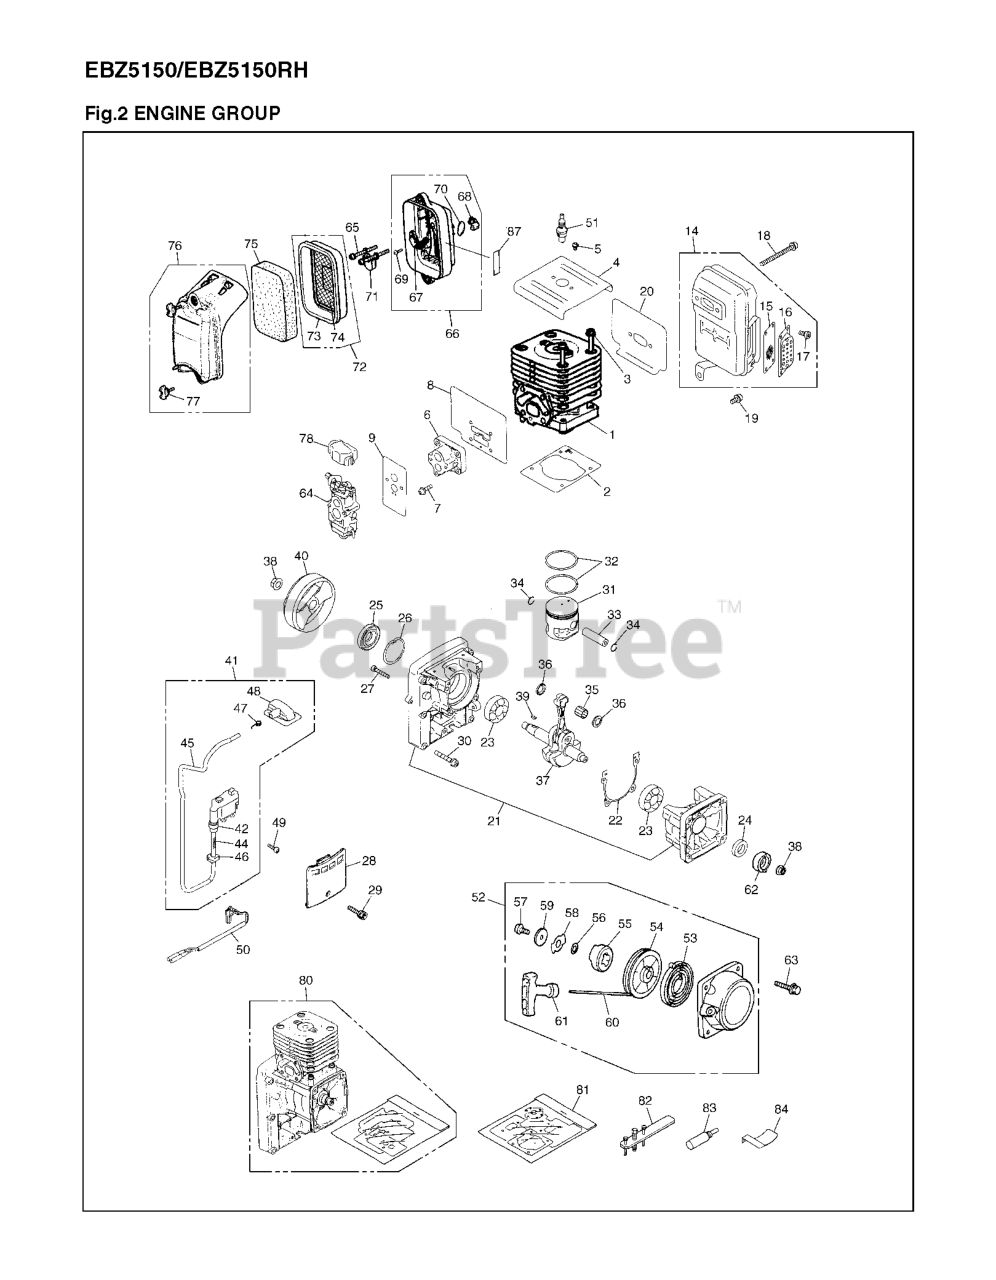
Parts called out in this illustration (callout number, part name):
1	CYLINDER
3	BOLT
4	CYLINDER COVER
6	INSULATION
8	GASKET,INSULATOR
14	MUFFLER ASSY
15	SPARK ARRESTOR SCREEN
16	EXHAUST DUCT
19	RP_BOLT
20	GASKET.MUFFLER
21	CRANKCASE
23	BEARING
26	RING
32	PISTON RING
33	PISTON PIN
34	SNAP RING
37	CRANKSHAFT
39	KEY
40	FLYWHEEL
41	COIL ASSY
42	HUB CAP 848F6L71E0
45	RP TUBE-A
46	GROMMET
50	CORD-COMP
51	PLUG CMR7H
52	STARTER ASSY
54	STARTER PULLEY
55	STARTER PAWL
58	RETAINER
59	WASHER
60	CHORD
62	PULLEY
64	CARBURETOR
66	CARBURETOR BODY
67	PLATE
69	SCREW
72	GASKET
74	SCREEN
75	AIR FILTER
76	COVER ASSY.
80	SHORT BLOCK
80	GASKET,INSULATOR
80	GASKET.MUFFLER
81	GASKET KIT
82	PULLER ASSY
83	STOPPER
84	GAUGE
87	LABEL,CHOKE
